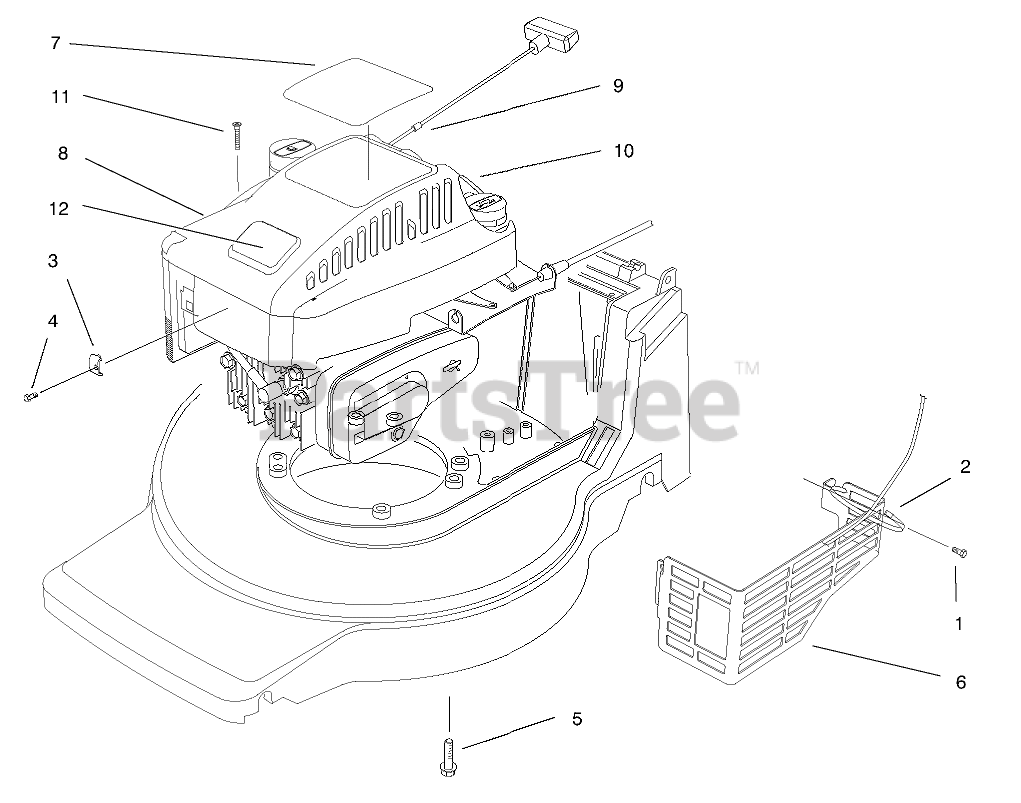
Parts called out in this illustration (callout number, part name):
1	SCREW-HWH
2	TIE-CABLE
3	CLAMP-CASING
4	SCREW-CLAMP
5	SCREW-HWH
6	SHIELD-MUFFLER
7	DECAL - RECOIL
9	STOP-ROPE
10	SHROUD-ENGINE
11	SCREW-PPH
12	PLATE-LOGO
